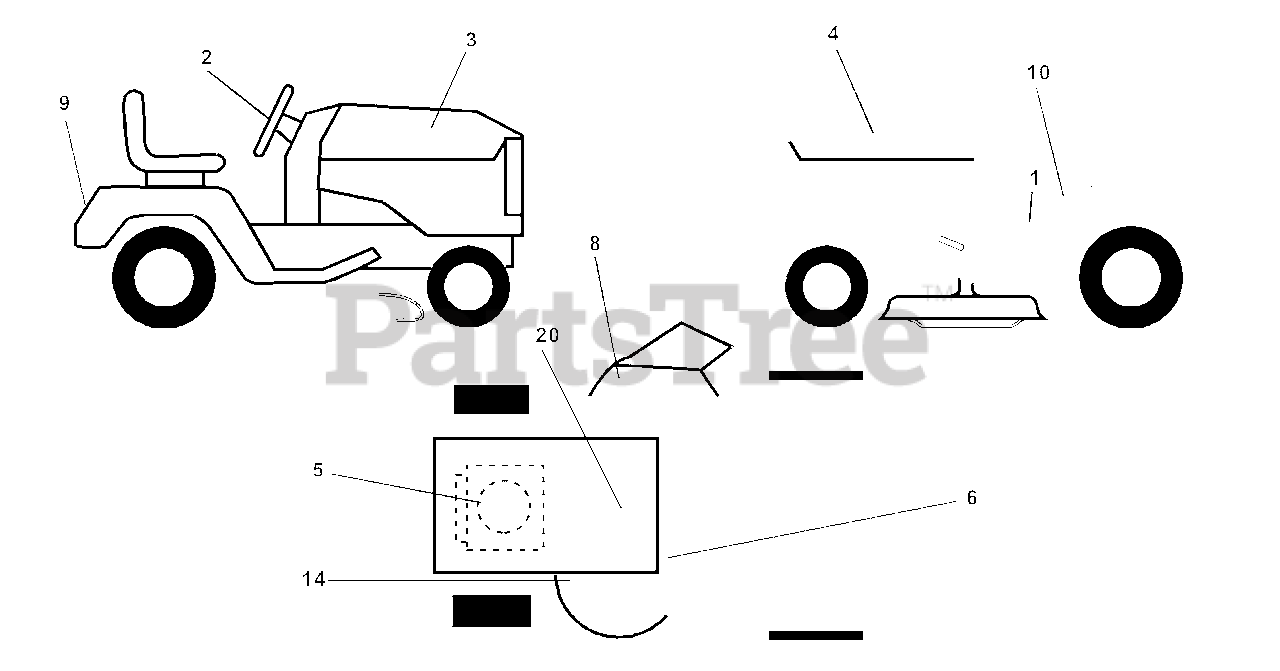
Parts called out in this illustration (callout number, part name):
1	Decal Oper Step Thru E/F
2	Decal Strg Wheel Logo
3	Decal Hood RH
4	Decal Hood LH
5	Decal Engine
6	Decal Dash Logo
8	Decal Warning
9	Decal Fender Husq
10	Decal Fender Danger E/F
14	Decal V-Belt Schematic
20	Decal Bat Dan/Psn
